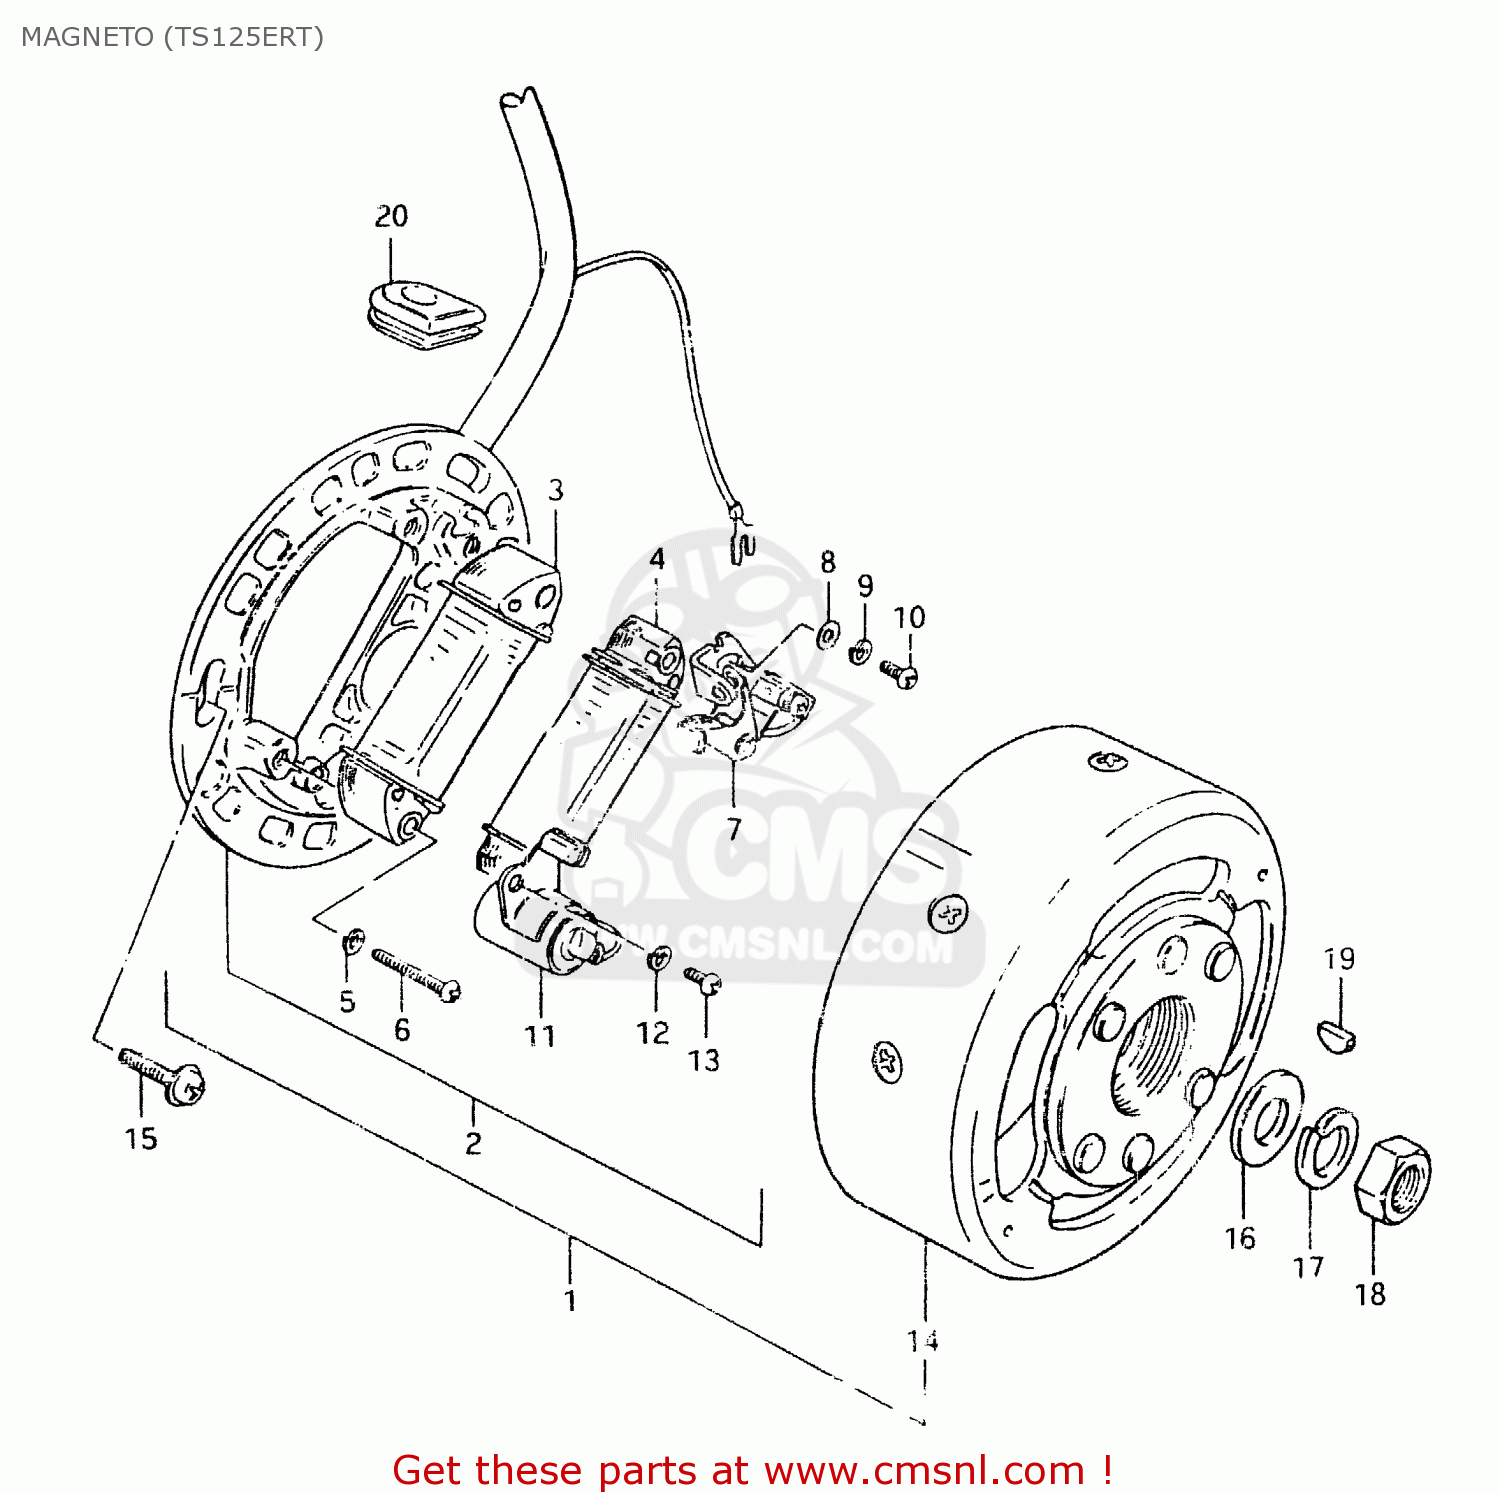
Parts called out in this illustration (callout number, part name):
1	MAGNETO ASSY
2	STARTER ASSY
3	COIL,LIGHTING
4	COIL,PRIMARY
5	LOCK WASHER
6	SCREW (4X30)
7	POINT ASSY,CONTACT
8	WASHER
9	LOCK WASHER
10	SCREW(4X10)
11	CONDENSER
12	LOCK WASHER
13	SCREW
14	ROTOR
15	SCREW(5X14)
16	WASHER
17	LOCK WASHER
18	NUT (10MM)
19	KEY
20	GROMMET
